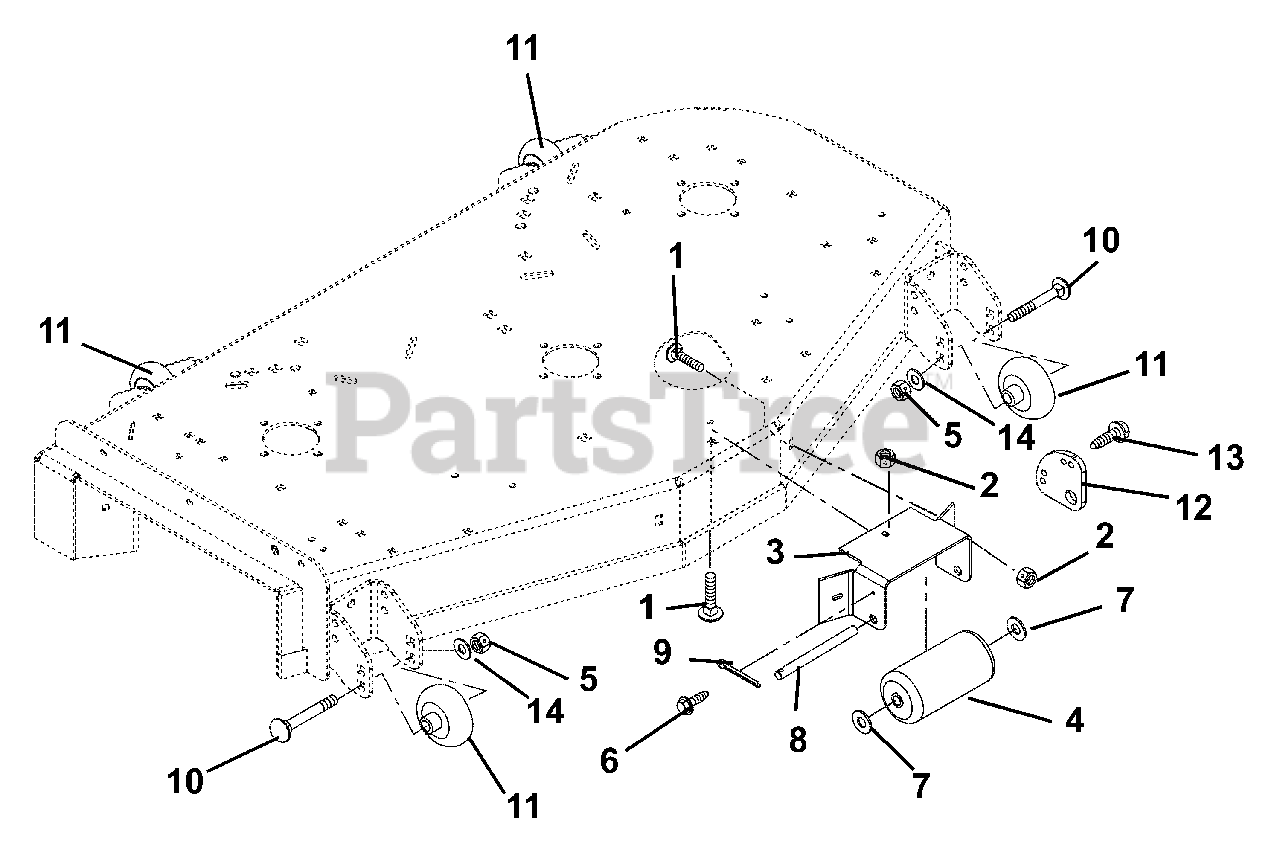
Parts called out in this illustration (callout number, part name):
1	@BLT-RDHDSQNK .38-16X1.00 G5YZ
2	@NUT-LK-TOP-FLG .38-16 YWZC
3	BRACKET - ANTI-SCALP ROLLER
5	@NUT-LK-NYL .50-13 YWZC
6	SCR-TAP .25-20X.75 HWH TR YWZ
7	@WSHR-FL-STL.656X1.31X.095 YWZ
8	PIN, 9.41 X .625
9	@PIN-CTR .25X2.00 YWZC
10	BLT-RDHDSQNK .50-13X5.00 GR5YZ
11	WHEEL, 3X5
12	ANTI-SCALP WASHER - RED
13	SCR-TAP.250-20X.62 HWH BLK ZC
14	@WSHR-FL-STL.531X1.06X.095YWZC
